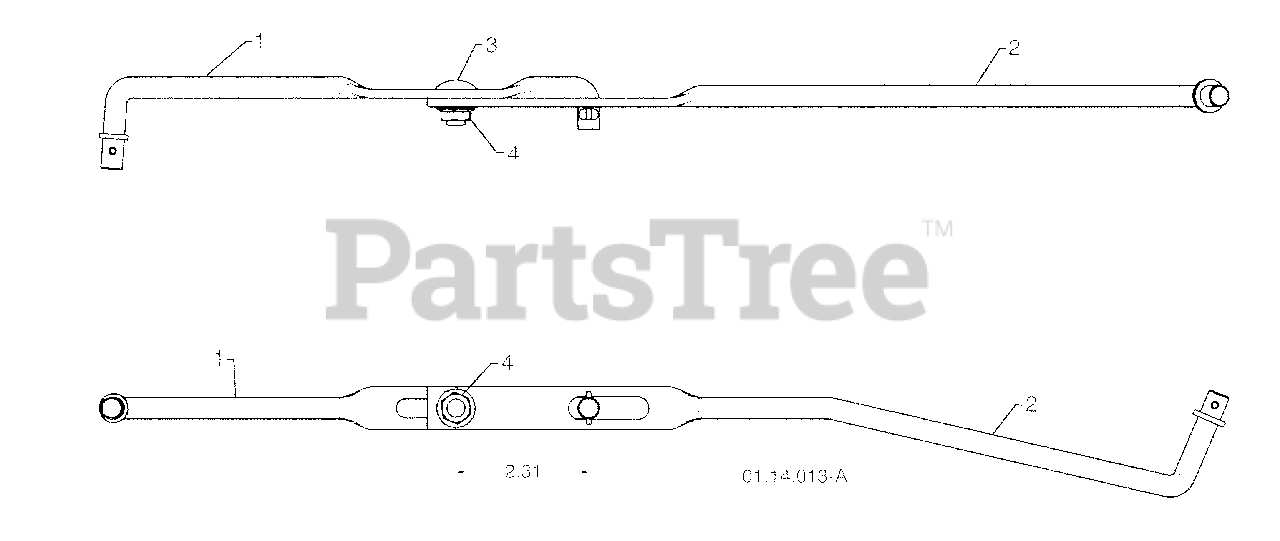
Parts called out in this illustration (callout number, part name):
1	SHIFTER ROD TOP
2	SHIFTER ROD BOTTOM
3	CARRIAGE BOLT 5/16-18 X .75
4	NUT 5/16-18
